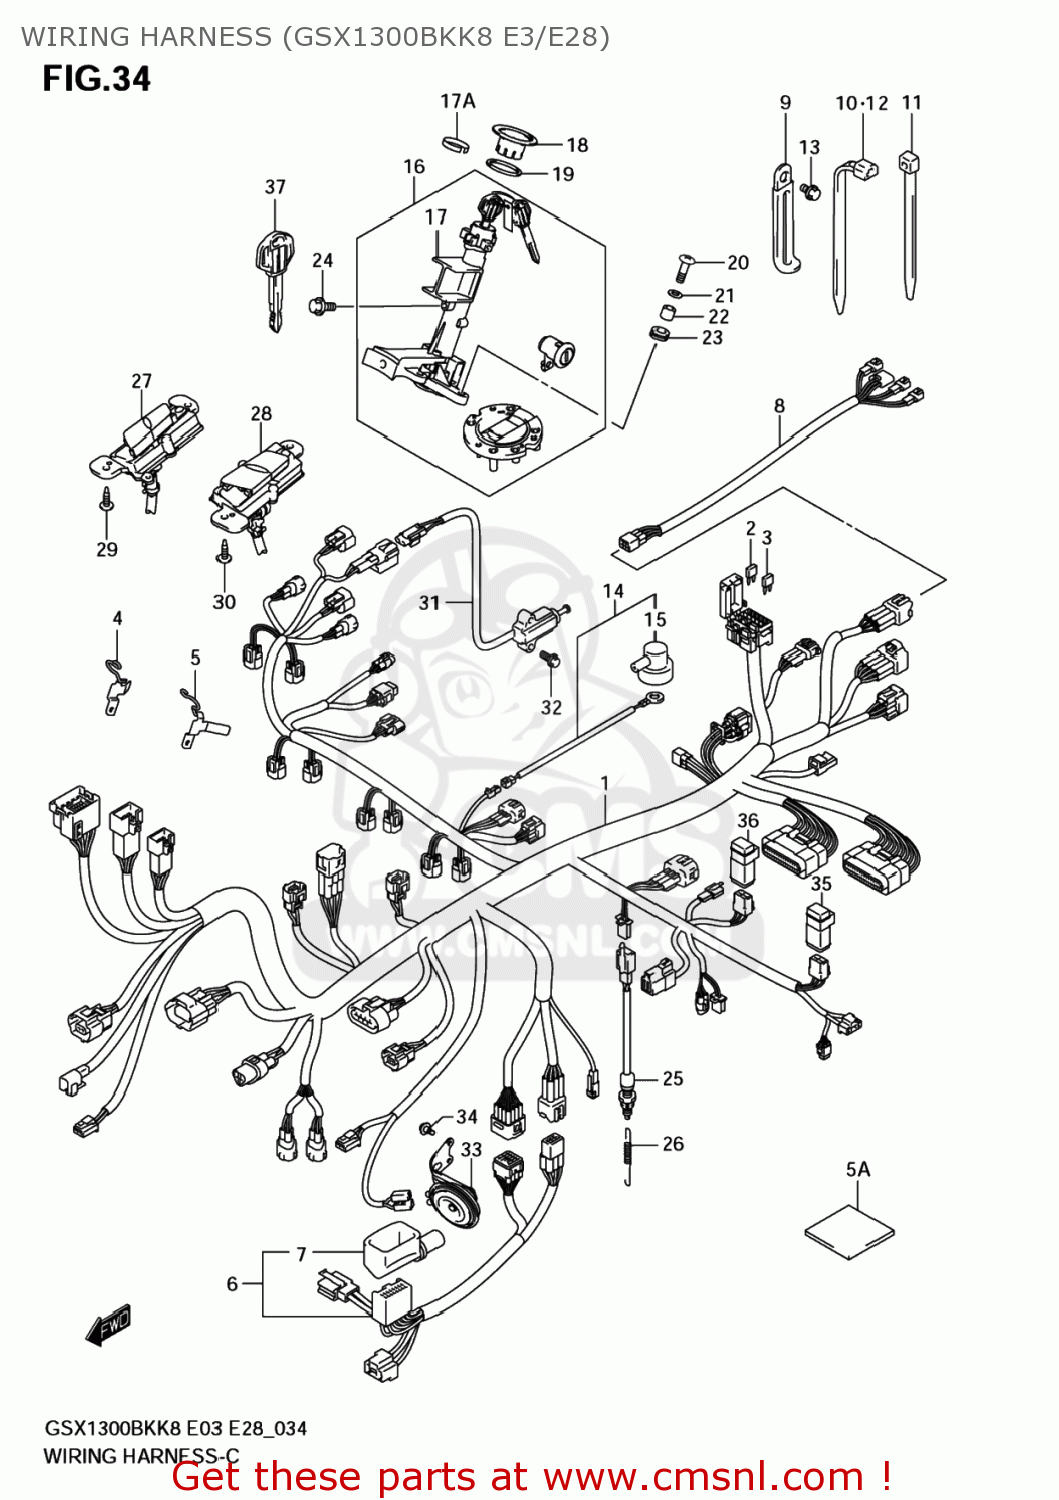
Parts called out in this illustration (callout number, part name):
1	HARNESS,WIRING
2	FUSE(10A)
3	FUSE(15A)
4	GUIDE,WIRING HARNESS,R
5	GUIDE,WIRING HARNESS,L
5A	PROTECTOR(80X80X2)
6	HARNESS,WIRING NO.2
7	COVER,CONNECTOR
8	WIRE,RR COMB
9	CLAMP(L:45)
10	CLAMP(L:125)
11	CLAMP(L:145)
12	CLAMP(L:190)
13	BOLT
14	WIRE,OIL PRESSURE SWITCH LEAD
15	CAP,OIL PRESSURE SWITCH
16	LOCK SET
17	LOCK ASSY,STEERING
17A	PROTECTOR,STEERING LOCK COVER
18	COVER,STEERING LOCK
19	CUSHION,STEERING LOCK COVER
20	SCREW(8X40)
21	WASHER(8.5X18X1.6)
22	SPACER(8.5X12X12)
23	CUSHION
24	BOLT
25	SWITCH ASSY,STOP LAMP
26	SPRING
27	SWITCH ASSY,CONTROLLER,R
28	SWITCH ASSY,CONTROLLER,L
29	SCREW
30	SCREW
31	SWITCH ASSY,SIDE STAND
32	BOLT
33	HORN ASSY
34	SCREW(6X16)
35	RELAY ASSY
36	RELAY ASSY
37	KEY,BLANK
